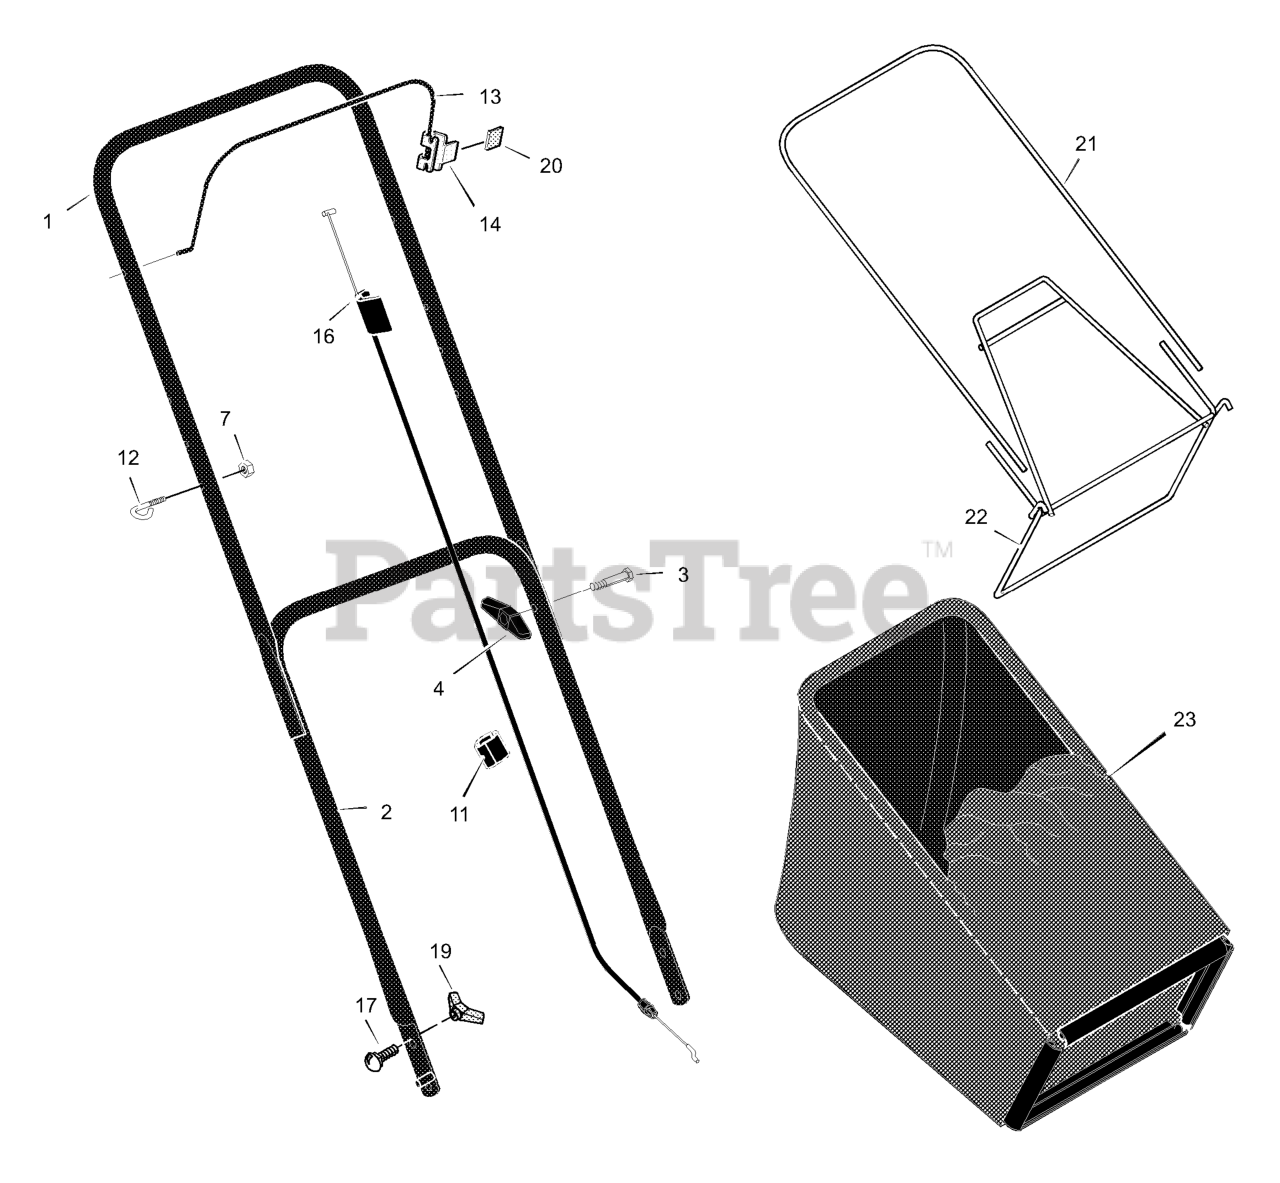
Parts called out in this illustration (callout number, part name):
1	Handle, Upper (Gray)
2	Handle, Lower (Gray)
4	Knob, Plastic
7	Locknut
11	Clip, Cable
12	Guide, Rope
13	Engine Stop Lever
14	Bracket, Stop Lever
16	Engine Stop Cable
17	Bolt, Carriage
19	Knob, Plastic
20	Sleeve, Vinyl
21	Frame, Top
22	Frame Assembly
23	Bag, Cloth
